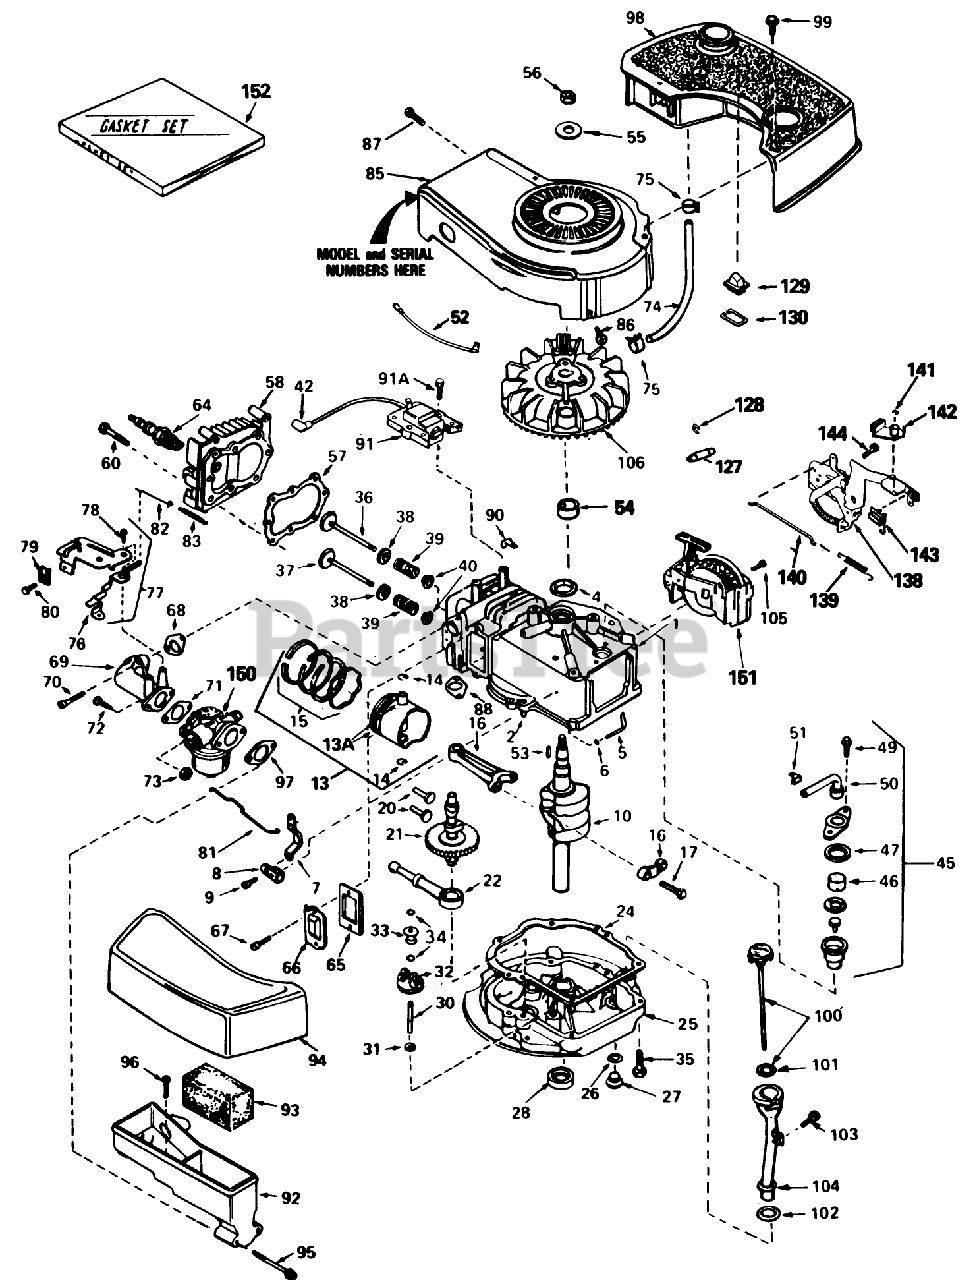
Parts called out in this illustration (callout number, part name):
1	Cylinder Assy. (Inc. #2 4)
2	Pin-Dowel
4	Seal-Oil
5	Rod, Governor (Incl. No. 36)
6	Washer-Flat
7	Governor Lever
8	Clamp-Lever, Governor
9	Screw
10	Crankshaft
13	Piston, Pin Ring Assy. (Std.) (Incl. Ref. #13A, 14 15)
13	Piston, Pin Ring Assy. (.010 oversize) (Incl. Ref. #13A, 14 15)
13	Piston, Pin Ring Assy. (.020 oversize) (Incl. Ref. #13A, 14 15)
13A	Piston Pin Assy. (Incl . Ref. . #14) (Std.)
13A	Piston Pin Assy. (Incl. Ref. #14) (.010 Oversize)
13A	Piston Pin Assy. (.020 oversize) (Incl. Ref. #14)
14	Ring-Retaining, Piston Pin
15	Ring Set (Std.)
15	Ring Set (.020" OS)
15	Ring Set (.010" OS)
16	Rod Assy., Connecting (Incl. Ref. #17)
17	Bolt-Rod, Connecting
20	Lifter-Valve
21	Camshaft(Mech.Comp. Release)
22	Oil Pump ASM
24	Gasket, Mounting
25	Flange Assy., Mounting (Incl. Ref. #26thru 30)
26	Gasket-Oil Drain
27	Plug Oil Drain
28	Seal Oil
30	Shaft-Governor
31	Washer-Flat
32	Governor Gear ASM
33	Spool-Governor
34	Ring-Retaining
35	Screw (1/4-20 x 1-1/4)
36	Valve, Intake (Std.) (Incl. Ref. #40)
36	Valve, Intake (1/32" oversize)(Incl. No. 40)
37	Valve, Exhaust (Std.)(Incl. No. 40)
37	Valve, Intake (1/32" oversize)(Incl. No. 40)
38	Cap-Upper Valve Spring
39	Spring-Valve
40	Cap-Valve, Spring
42	Cover-Spark Plug
45	Breather Assy. (Incl. Ref. #46 thru 51)
46	Element-Breather
47	Gasket-Breather
49	Screw (10-24 x 9/16)
50	Tube, Breaker
51	Clip, Breather
52	Ground Wire
53	Key-Flywheel
54	Spacer
55	Washer-Belleville
56	Nut-Flywheel
57	63573 GIL 42 SNWTHW
58	Head-Cylinder
60	Screw (5/16-18x1-1/2)
64	Plug, Spark (J17LM or equiv.)
64	Plug, Spark (Champion RCJ-8)
65	Gasket-Breather
66	Cover-Valve
67	Screw
68	Gasket-Intake
69	Pipe, Intake (Incl. No. 68)
70	Screw (1/4-20 x 1)
71	Gasket-Carburetor
73	Nut and Lock Washer (1/4-28)
74	Line-Fuel
75	Clamp-Line, Fuel
76	Lever Control
77	Control Assy., Speed (Incl. Nos, 76, 78 89)
78	Screw, Hex Washer Hd Shoulder Self-Tap
79	Conduit
80	Screw (10-32 x 3/8)
81	Link-Throttle
82	Link Governor Spring
83	Spring Governor
85	Housing-Blower
86	Screw (1/4-20x19/32)
87	Screw (10-24 x 9/16)
88	Gasket Exhaust
90	Clip-Wire
91	Solid State
91A	Screw
92	Body Air Cleaner
93	Filer, Air
94	Cove, Air Cleaner
95	Screw Fil Hd.
96	Screw, Hex Hd.
97	Gasket-Air Cleaner
98	Tank, Fuel
99	Screw (10-32 x 35/64)
100	Dipstick, Oil (Incl. Ref. #101)(Twist Lock)
101	O-Ring
102	Gasket
103	Screw (10-32 x 1/2)
104	Tube-Oil Fill
105	Screw (1/2-20x5/8)
106	Flywheel
127	Coupling, Starter Rope
128	Staple, Rope Retainer (Strip of 25 Pieces)
129	Pulley Assy., Starter
130	Retainer, Pulley
138	Bracket Assy.
139	Spring-Extension
140	Link-Control
141	Ring-Retaining
142	Lever-Brake
143	Terminal
144	Screw-Hex. Hd.
150	Carburetor (Incl. Ref. #71)
151	Starter, Sidemount rewind
152	Gasket Set
